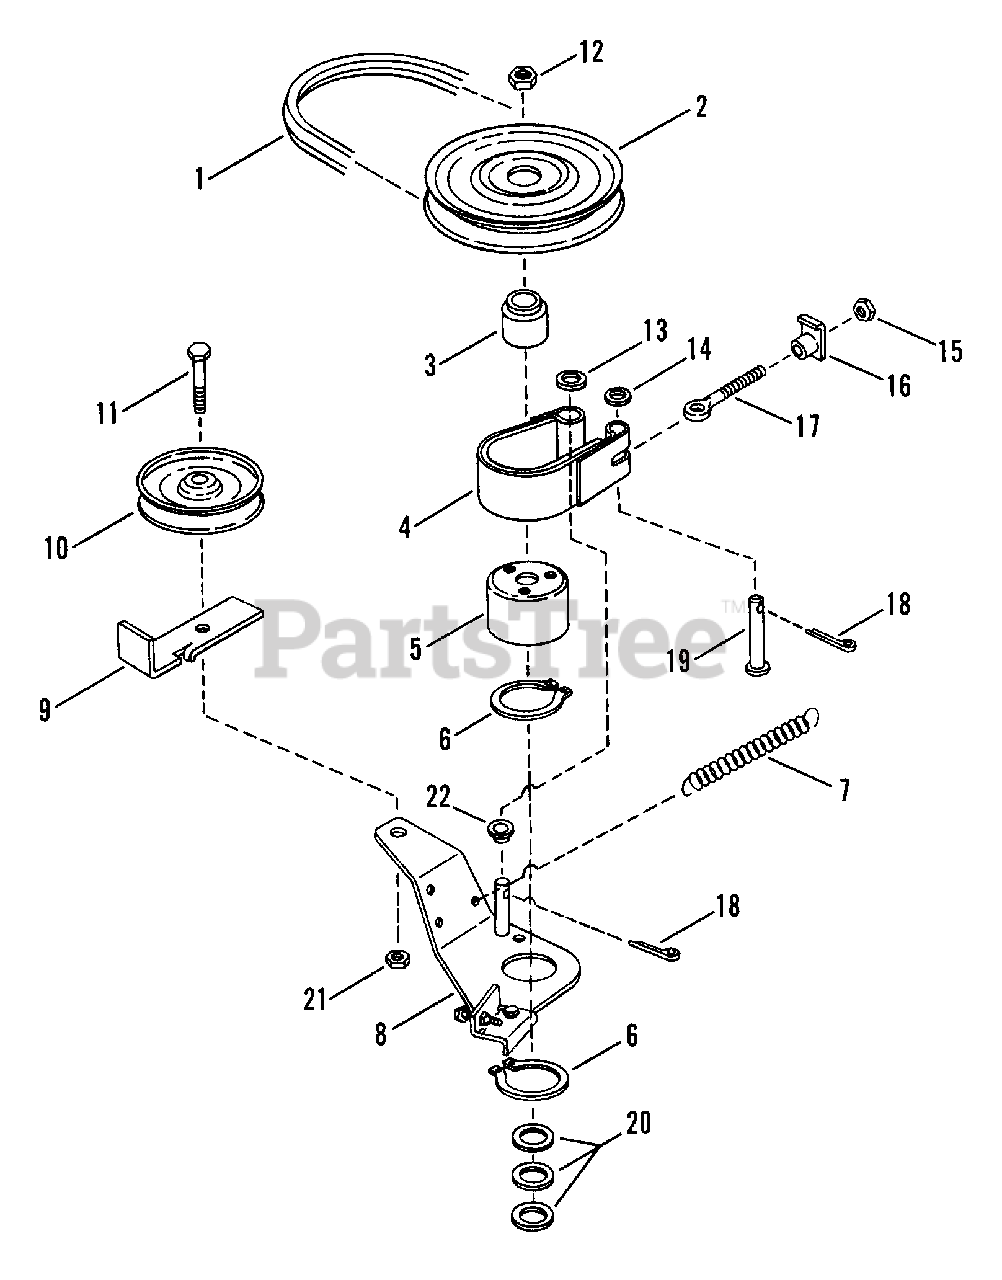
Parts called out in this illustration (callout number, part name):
1	BELT, Blade
2	PULLEY, Spindle
3	HUB, Pulley
4	BAND, Brake Assembly
5	DRUM, Blade Brake
6	RING, 2" External Retaining
7	SPRING, Blade Brake
8	ASSEMBLY, Idler Arm
9	RESTRICTOR, Belt
10	PULLEY, Idler
11	SCREW, 3/8-24 x 1-3/4" Hex Head Cap
12	NUT, 3/4-16 Hex Jam
13	WASHER, 3/8 SAE
14	WASHER, 1/4 SAE
15	NUT, 1/4-20 Hex
16	TEE-NUT, 1/4-20
17	EYE-BOLT, 1/4-20
18	COTTER-PIN, 3/32 x 3/4"
19	PIN, 1/4 Clevis
20	WASHER
21	NUT, 3/8-24 Hex Lock
22	SPACER
